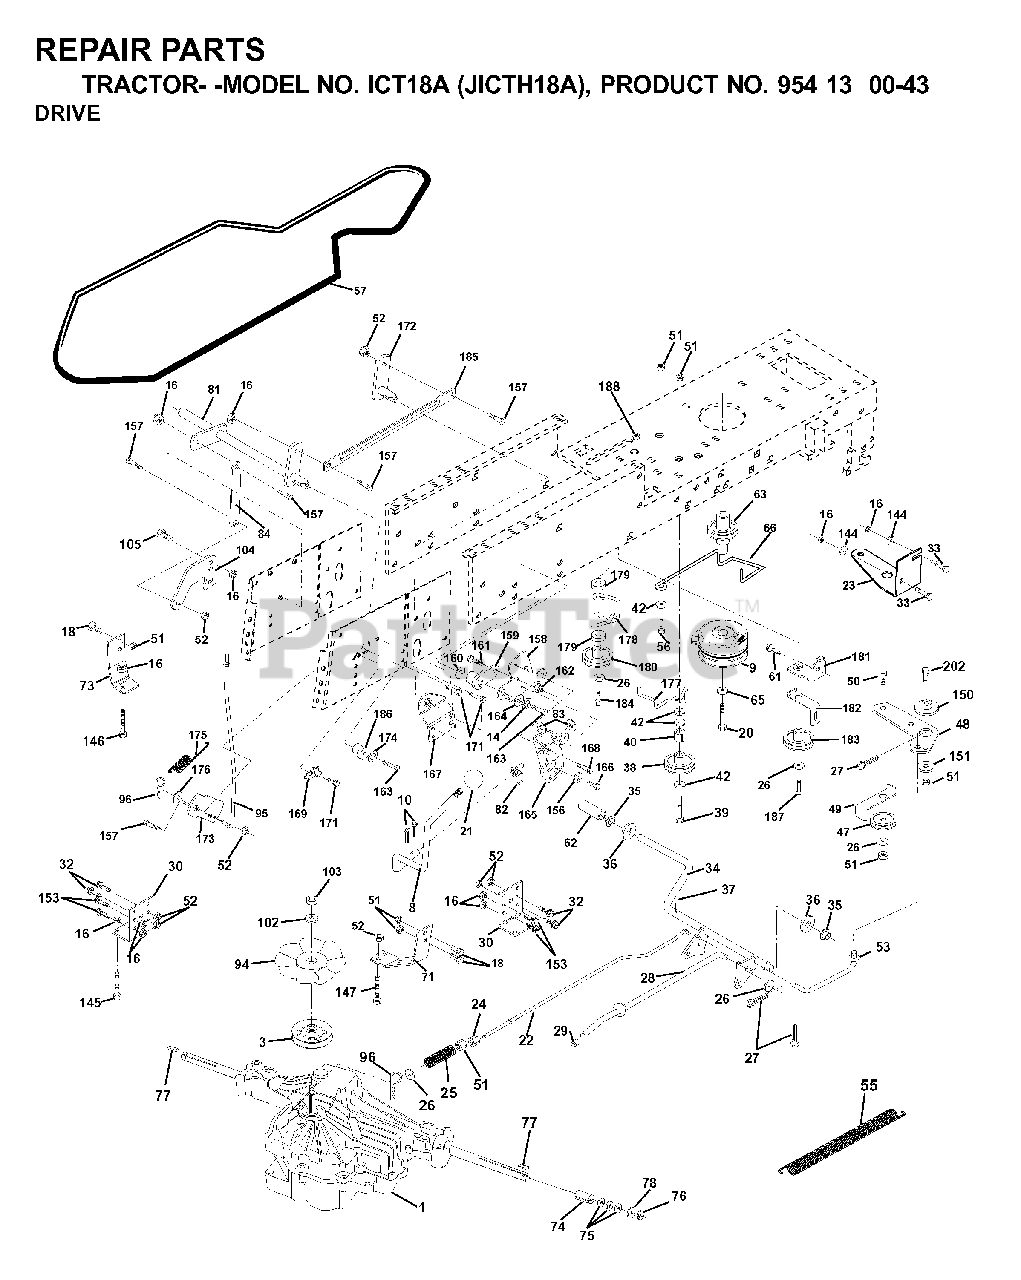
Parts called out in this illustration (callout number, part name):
3	PULLEY, TRANSAXLE
8	ROD SHIFT
10	PIN COTTER
14	LOCKWASHER
16	NUT.71038.31-18.HEX.NYLOCK
19	NUT
20	BOLT HEX
21	PISTOL KNOB
23	BRACKET
24	NUT
25	SPRING ROD LT
27	COTTER PIN
28	ROD BRAKE PARK LT
29	PLUNGER CAP
30	BRKT, TRNSXLE MNT 20"
32	BOLT
33	BOLT
35	BEARING.NYLON
36	WASHER LT
37	DRIVE PIN
38	PULLEY.FLAT
42	WASHER
47	IDLER PULLEY
48	BELLCRANK, CLUTCH
49	RETAIN BELT
50	BOLT
51	LOCKNUT
52	LOCKNUT
53	LINK, CLUTCH LT
55	SPRING, RETURN LT
61	SCREW 3/8-16X3/4
62	PEDAL COVER T
63	PULLEY, CLUTCH ELECT EVX
65	LOCKWASHER
66	KEEPER BELT ENGINE
71	STRAP LH TORQUE
73	STRAP TORQUE RH HYDRO
74	SPACER SPLIT
76	E-RING LT
77	SQUARE KEY
82	SPRING,TORSION
83	WASHER
84	LINK TRANSAXLE
94	FAN 7" HYDRO
96	RETAINER M
103	NUT.HEX.1/2-20
104	CONTROL ARM
144	WASHER
146	BOLT
150	BUSHING.BELLCRANK.GRD.DR
151	WASHER 12/32X2X10GA
153	BOLT RB
156	WASHER.SRRTD.5/16
157	BOLT SHOULDER 5/16-18
158	BRACKET
159	HUB
161	BOLT
162	NUT.CROWNLOCK.1/4
165	RP BRACKET
167	BRACKET
168	BOLT.SHOULDER.5/16-18X
169	PLATE.FASTENING.CROSS.SHAFT
174	LOCKWASHER
175	SPRING.BYPASS.CRD
176	WASHER
180	PULLEY.FLAT.IDLER
182	KEEPER BELT
183	PULLEY.V-IDLER
184	SCREW.HXWSH.3/8
187	SCREW
188	SNAP BUSHING T
202	BOLT.3/8-16X1.50
